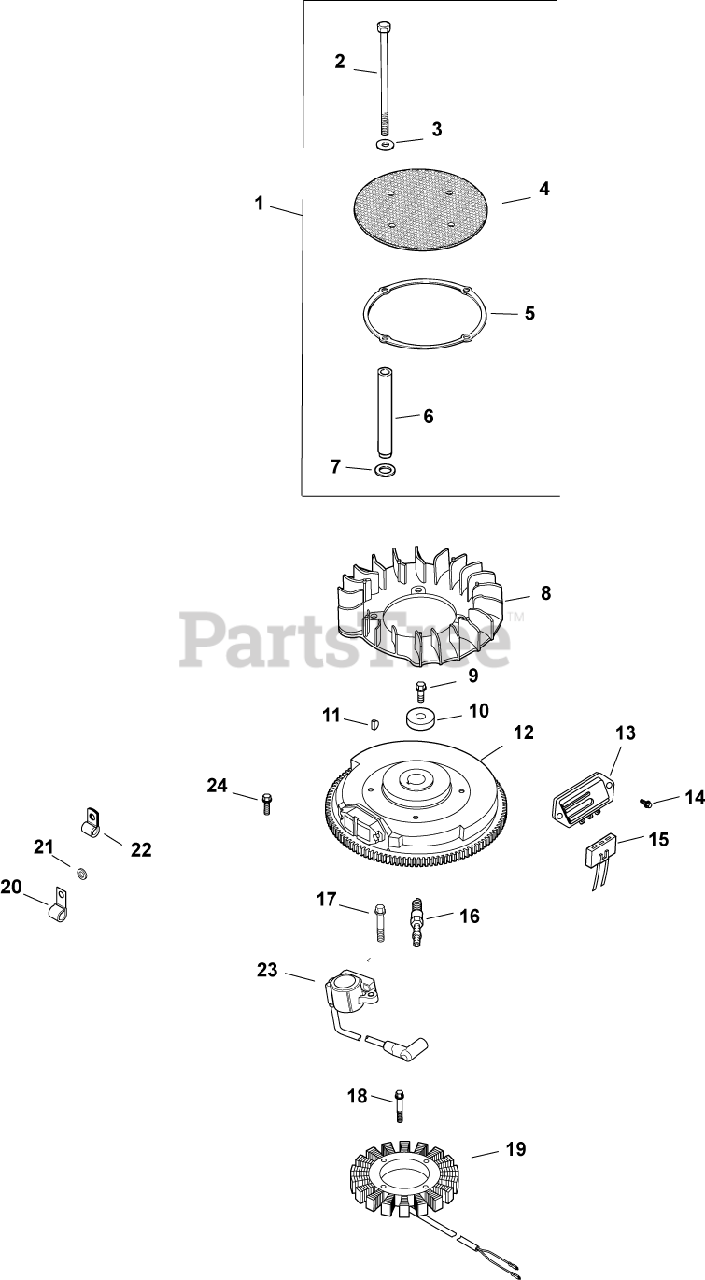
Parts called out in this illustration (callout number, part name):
1	KIT, CHOPPER SCREEN
2	SCREW, CAP M6X1.0X99.5
3	WASHER, FLAT 1/4" (O.D. 5/8")
4	SCREEN, GRASS
5	RING, SUPPORT USE 25 141 08-S
7	WASHER, SPRING 10 MM
9	SCREW, FLG M10X1.5X45 - (#25086361S)
10	WASHER, FLAT 13/32"
11	KEY, 3/16" X 5/8"
12	FLYWHEEL ASSEMBLY-USE 24 025 58-S
13	REG/RECT-15 AMP (KM)-USE 41 403 10-S
14	SCREW, PHL HD #11-16X7/8"
15	CONNECTOR, BODY (KM)-USE 25 155 41-S
16	PLUG, SPARK (PRO SERIES)
17	SCREW, M5X0.8X25 - (#25086402S)
18	SCREW, SKT SET #10-24X1/4"
19	KIT, 15 / 20 AMP STATOR
20	CLIP, TUBE & WIRING (KM)
21	WASHER, FLAT 1/4" (O.D. 1/2")
22	CLIP, CABLE
23	MODULE, IGNITION
24	SCREW, FLG THD FRM M5X.8X20-(#25086399S)
2458452-S	MODULE, SPARK ADV -USE 24 584 89-S
